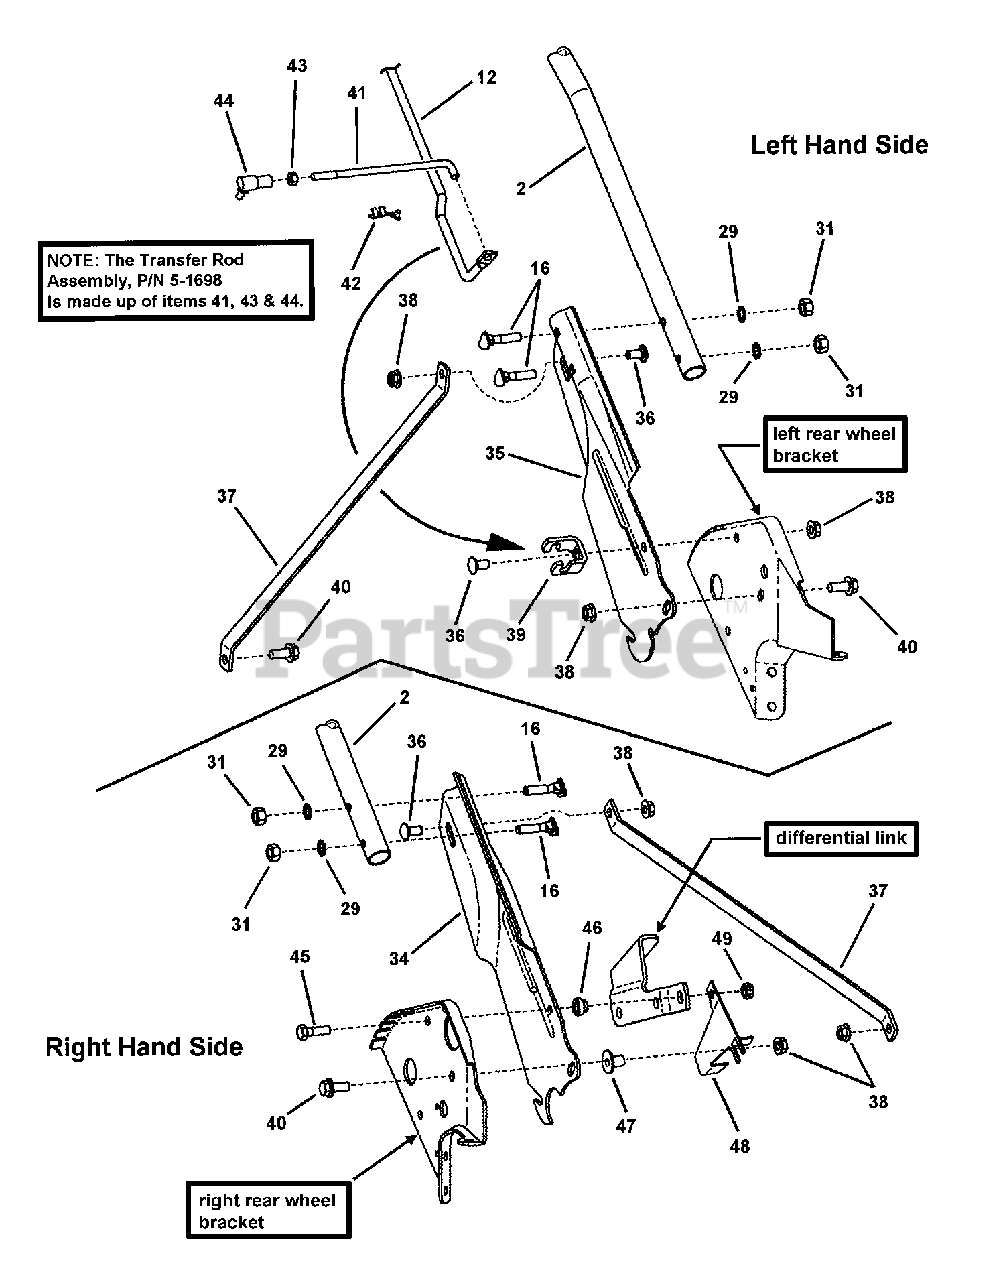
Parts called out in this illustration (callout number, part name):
2	HANDLE, Middle
12	LEVER, Speed Control
16	BOLT, 5/16-18 x 1-1/2" Curved Head Carriage
29	WASHER, 5/16" Internal Tooth Lock
31	NUT, 5/16-18 Hex, GR5
34	HANDLE, Lower Right Hand
35	HANDLE, Lower Left Hand
36	BOLT, 5/16-18 x 5/8" Short Neck Carriage GR5
37	STRAP, Handle
38	NUT, 5/16-18 Hex Flange Lock GR5
39	ANCHOR, Speed Control
40	BOLT, 5/16-18 x 5/8" Hex Flange Lock GR5
41	ROD, Transfer (1/4-28 thread)
42	CLIP, Transfer Rod
43	NUT, 1/4-28 Hex, GR5
44	BALL JOINT (1/4-28 thread)
45	SCREW, 5/16-24 x 1" Hex Head Cap, GR5
46	BUSHING, Differential
47	NUT, 5/16-18 Tee
48	GUIDE, Lower V-Belt
49	NUT, 5/16-24 Hex Center Lock GR5
